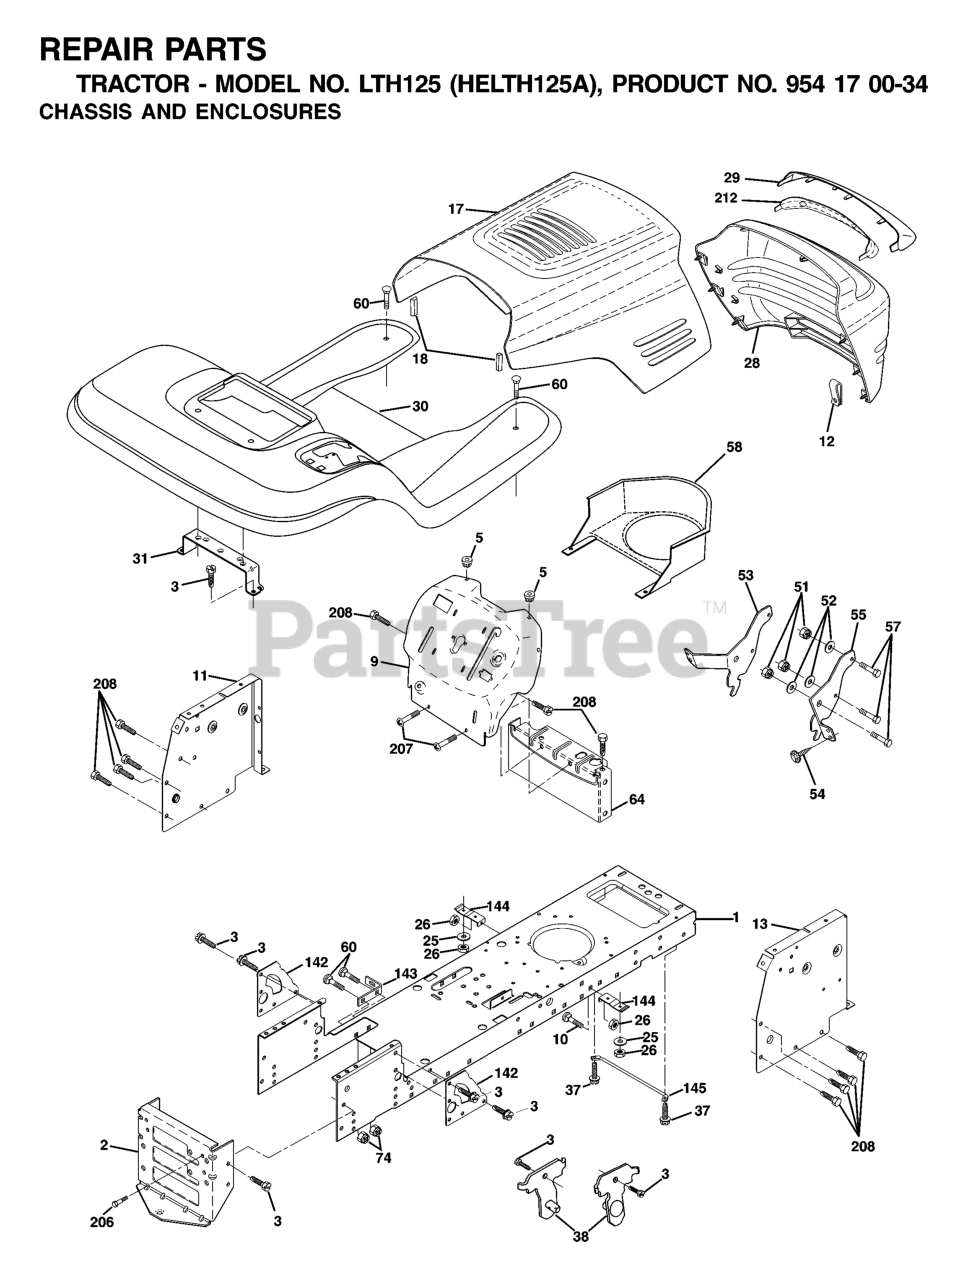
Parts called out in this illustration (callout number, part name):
2	DRAWBAR
3	SCREW 3/8-16X3/4
5	BUMPER.RUBBER.HOOD
9	DASH
10	BOLT D
11	PANEL DASH LH
13	PANEL DASH RH
17	HOOD ASM.
18	BUMPER HOOD T
25	WASHER
26	NUT
28	LENS
29	LENS
30	FENDER FOOTREST
31	BRACKET.SUPPORT.FENDER
37	Screw 5/16-18 x 1/2 Hex, Self Tapping 5/16-18 x 1/2
38	BRACKET
51	LOCKNUT.NYLOC.1/4-20
53	BRACKET.GRILLE.LH
54	SCREW.HEX.WS.HD.8-18 X 7/8
57	BOLT
58	AIR DUCT P/L/LT
60	Bolt - Rd. Hd. Sq. Neckiage 3/8 16 x 3/4
64	DASH LOWER
142	PLATE
143	BRACKET, SWAY BAR
144	BRACKET FOOTREST
145	ROD PIVOT CHASSIS/HOOD
206	SHOULDER BOLT 5/16-18TT
207	SCREW, 5/16-18 X 1/2
208	SCREW 3/8-16X1/2
212	REPL BY 532 1745-03
